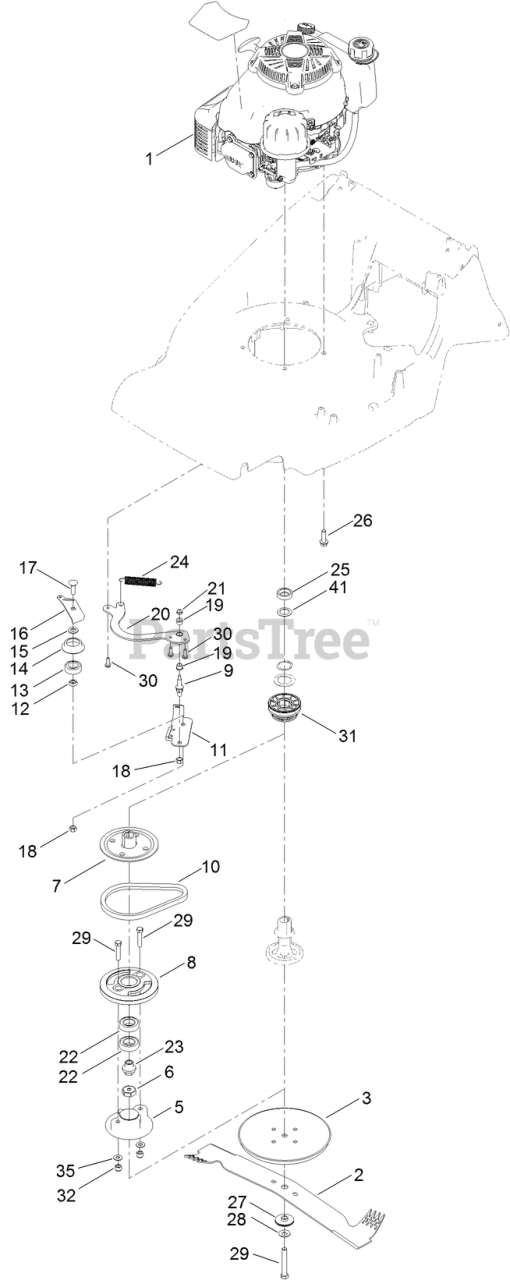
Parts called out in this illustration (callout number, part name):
1	ENGINE-KAWASAKI, FJ180V, BBC
2	CUTTERBAR
3	DISC-FRICTION
5	SPACER-BLADE, BBC
6	NUT-RETAINING
7	PULLEY-DRIVE
8	DRUM-BBC
9	BOLT-SHOULDER
11	PLATE-BRAKE
12	SPACER-BEARING
13	BEARING-BALL
14	RETAINER-BELT
15	SPACER
16	PLATE-TENSIONER
17	SCREW-CARR
18	LOCKNUT
19	BUSHING-FLANGE
20	ANCHOR PLATE ASSEMBLY
21	NUT-HF
22	BEARING
23	BBC SHAFT NUT
24	SPRING-TENSION, BRAKE
25	SPACER-RETAINING
26	SCREW-TAPTITE, UNC
27	SPACER-DISTANCE, CUTTERBAR
28	WASHER-LOCK
29	BOLT
30	SCREW-TAPTITE
31	PULLEY-ENGINE
32	NUT-HEX, NI
35	WASHER-PLAIN
41	SPRING-DISK
